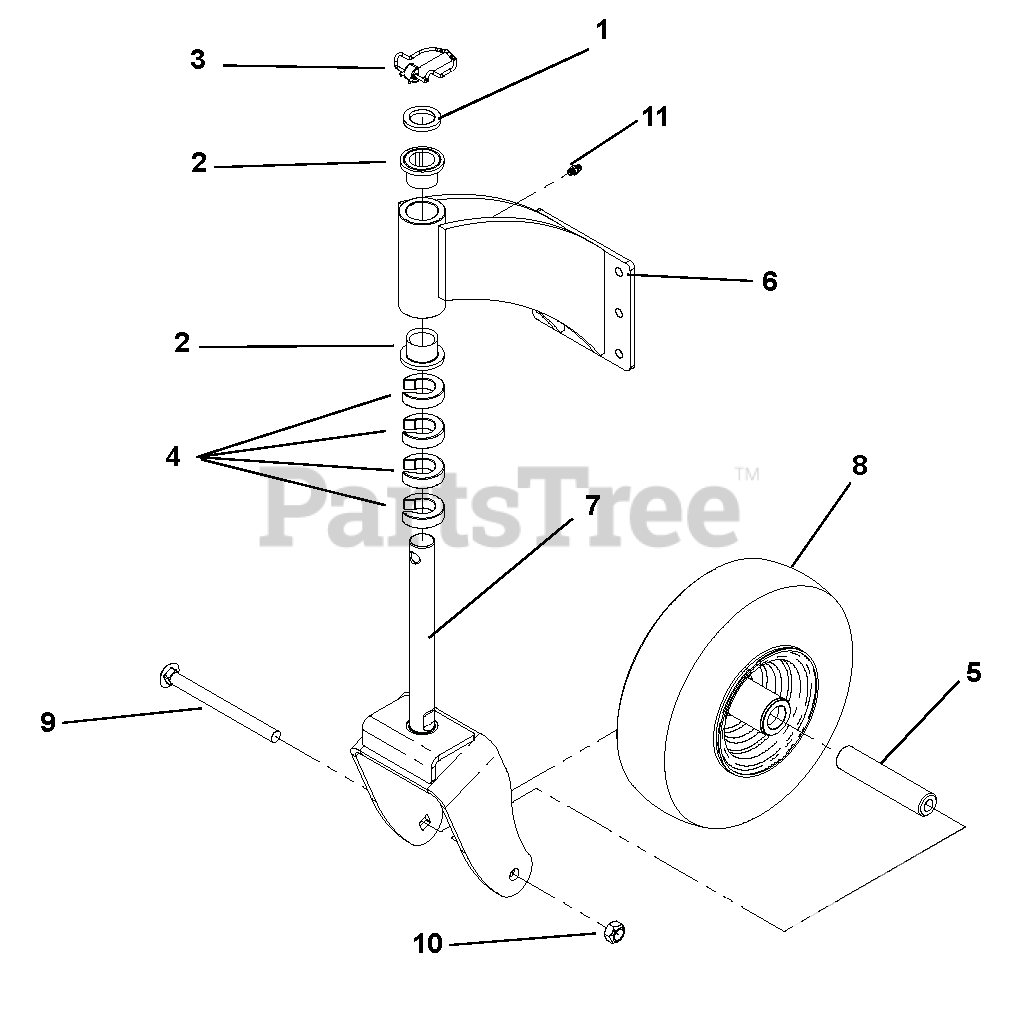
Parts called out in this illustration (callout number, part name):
1	BUSHING, 1.03X1.501.179
2	BRG, FLG 1.00X1.25X1.00
3	PIN, LOCK .438 X 2.00
4	C-SPACER, 1.00X1.77X.50
5	TUBE, 1.00X.50X4.76
6	WLDT, CASTER MOUNT ARIENS 52
7	WLDT, FR WHEEL FORK ARIENS 52
8	WHEEL, FRONT 11X4X5
9	BOLT, 1/2-13X6.00 CRG Y
10	LOCKNUT, 1/2-13 CROWN Y
11	GREASE ZERK, 1/4-28 STR .69 LG
